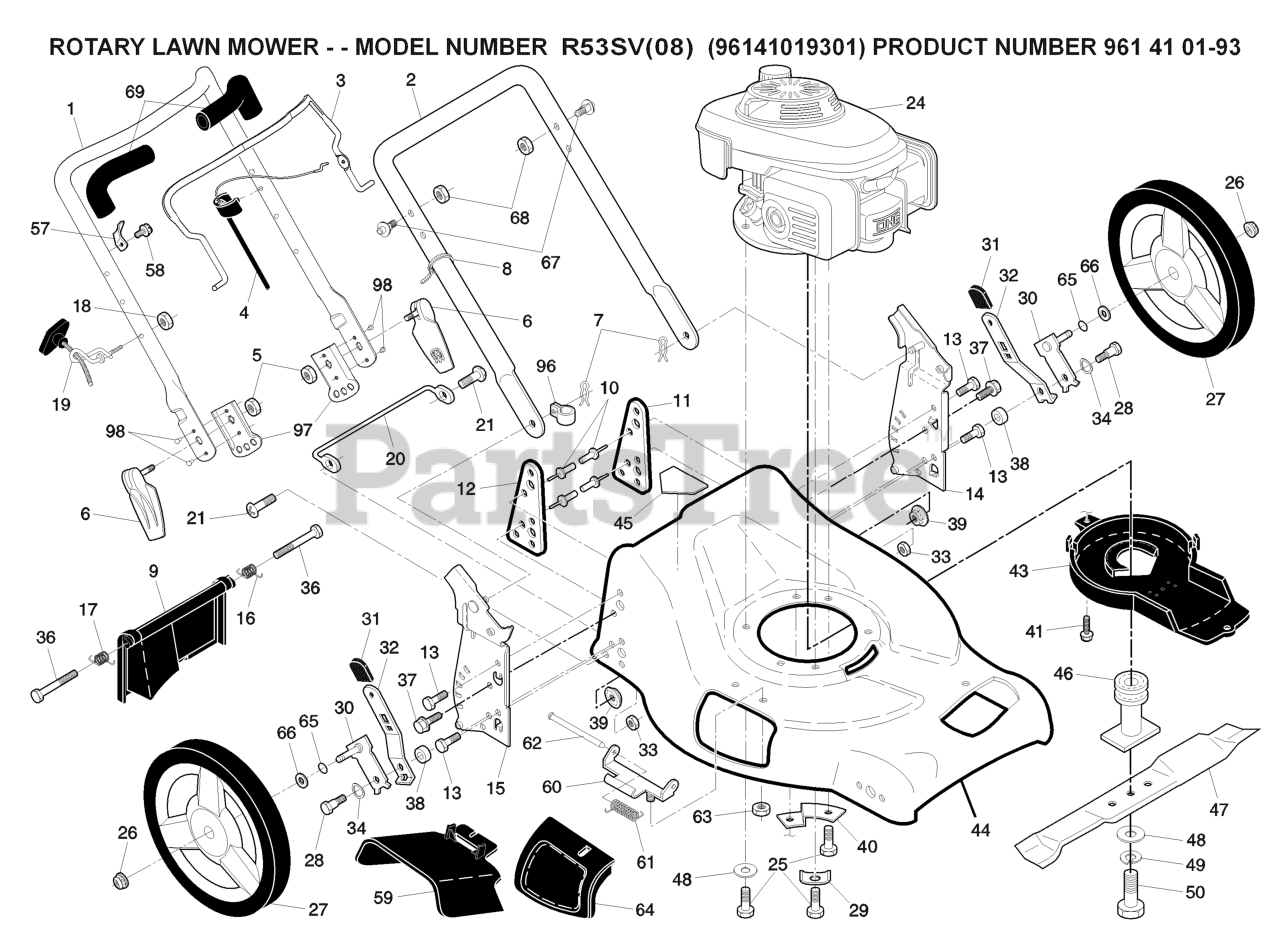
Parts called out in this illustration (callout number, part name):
1	HANDLE.ASM.UP.W/ADJ.BKT.21FGD
2	HANDLE.LOWER.GREY
3	BAIL CONTROL
4	CABLE.ASM.ZONE.CONTROL
5	NUT.HEX.FLANGE.1/4
6	ASM.QUICK.RELEASE
7	HAIRPIN COTTER
8	TIE GUIDE
9	REAR DOOR ASSEMBLY
10	RIVET BLIND
11	SUPPORT BRACKET LH
12	BRACKET.SUPRT.RH.21.FWGD
13	SCREW 14-20 X 5/8
14	BRACKET.ASM.HND.21FG.EZ.L.HW
15	BRACKET.ASM.HND.21FG.EZ.R.HW.P
16	SPRING.REAR.DOOR.EZ.21.LT
17	SPRING.REAR.DOOR.EZ.21.RT
18	NUT
19	RB GUIDE.ROPE.STD.BLK.ZIN WSL
21	SCREW
25	BOLT 3/8-16X1-1/8
26	NUT.HEX.FLANGE.3/8-16.LOCKNUT
27	WHEEL ASSY
28	SHOULDER BOLT 5/16-18
29	WASHER.ENGINE.BZP
30	ARM.ASM.AXLE.REAR.5/9.POS.BZP
31	SELECTOR KNOB
32	SELECTOR SPRING
33	NUT.71038.31-18.HEX.NYLOCK
34	WASHER.CURVED.CYLINDRICAL
37	BOLT.FIN.HEX.5/16-18X3/4
38	SPACER.HEIGHT.ADJUSTER
39	NUT.FLANGE.5/16
40	BRACKET
41	SCREW.HEX.WSH
43	DEBRIS SHIELD
44	KIT.HSG.21.FGD.MC.ORG.CE SYM
45	DECAL.INTERNATIONL.CUTFINGER
46	Blade Adapter / Pulley
47	BLADE.21.PUSH
48	WASHER,HARDEN
49	LOCKWASHER
50	SCREW, HEX HD 3/8-24 X 1-3/8
57	BRACKET
59	DEFLECTOR.CLIPPIN.21.FGD
60	BRACKET.ASM.HINGE.21.FWGD.
61	SPRING.TORSION
62	ROD.HINGE.21
63	LOCKNUT.NYLOC.1/4-20
64	DOOR.MULCH.21.REAR.FWGD
65	O-RING..070X.487.NEOPRENE
66	WASHER.FLAT.1/2
67	STUD.QUICK.ADJUST
68	NUT.LOCK.5/16-18
69	GRIP.HANDLE.FOAM.WIDE.(1 SIDE)
96	CLIP.CABLE.BLK
97	BRACKET.ADJ.3POS.GREY
